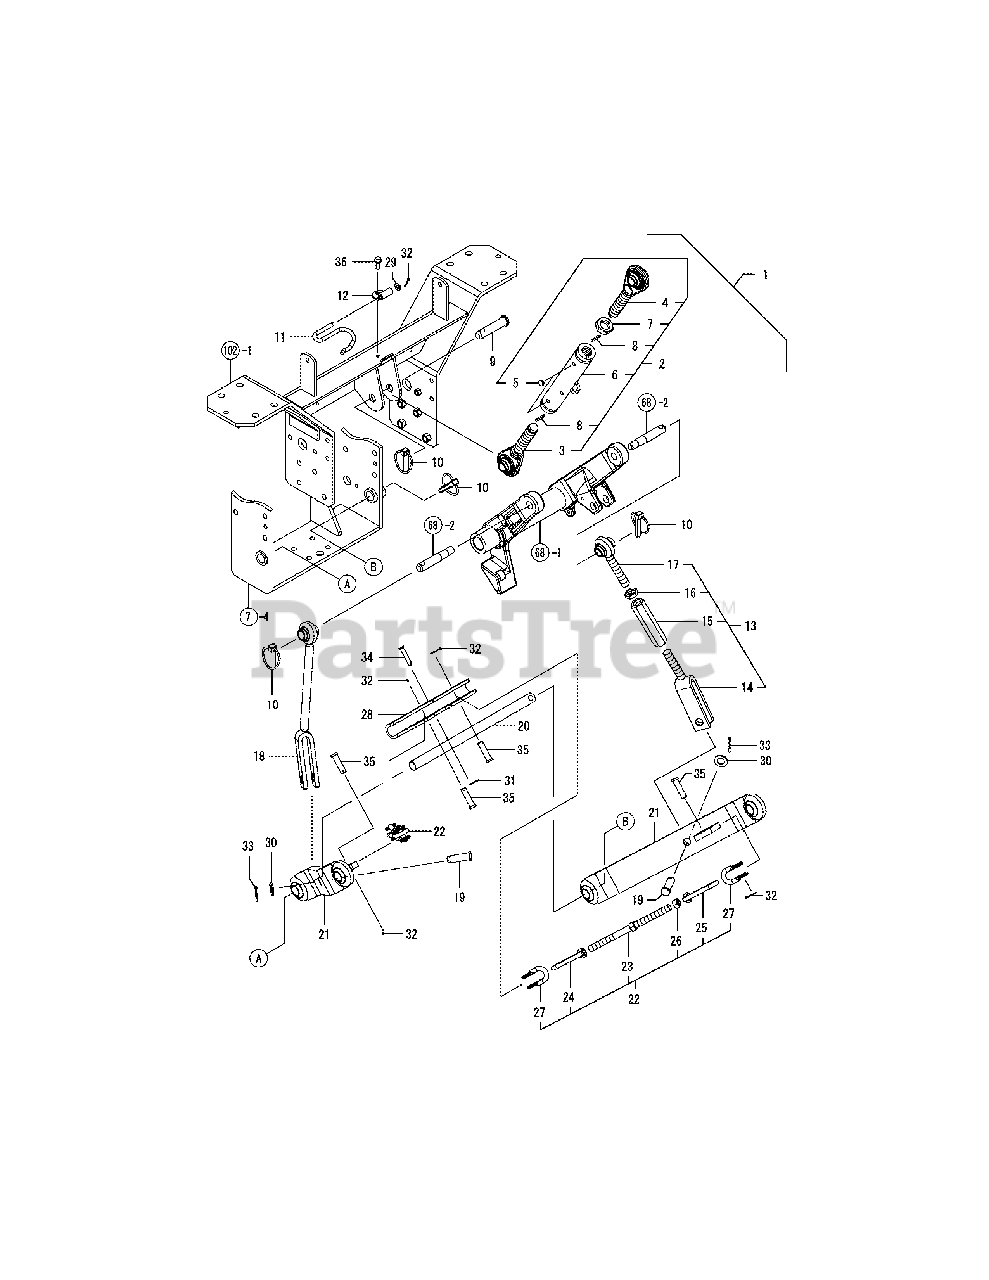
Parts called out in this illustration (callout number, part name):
3	Eye Bolt L Cmp
4	Eye Bolt R Cmp
6	Turnbackle Assy
7	Turn Backle Cmp
9	Pin, Upper Link
10	Pin Assy, Lintch
12	Plate (Toplink
13	Rod Cmp, Lift R
14	End Assy,Lower
17	End Assy,Upper
18	Rod Cmp, Lift L.H.
20	Bar, Lower Link
21	Link Assy, Lower
22	Chain Assy, Check
23	Turnbackle Assy
24	Eyenut, Chain L
25	Eyenut, Chain R
35	Pin, 12 X 40
